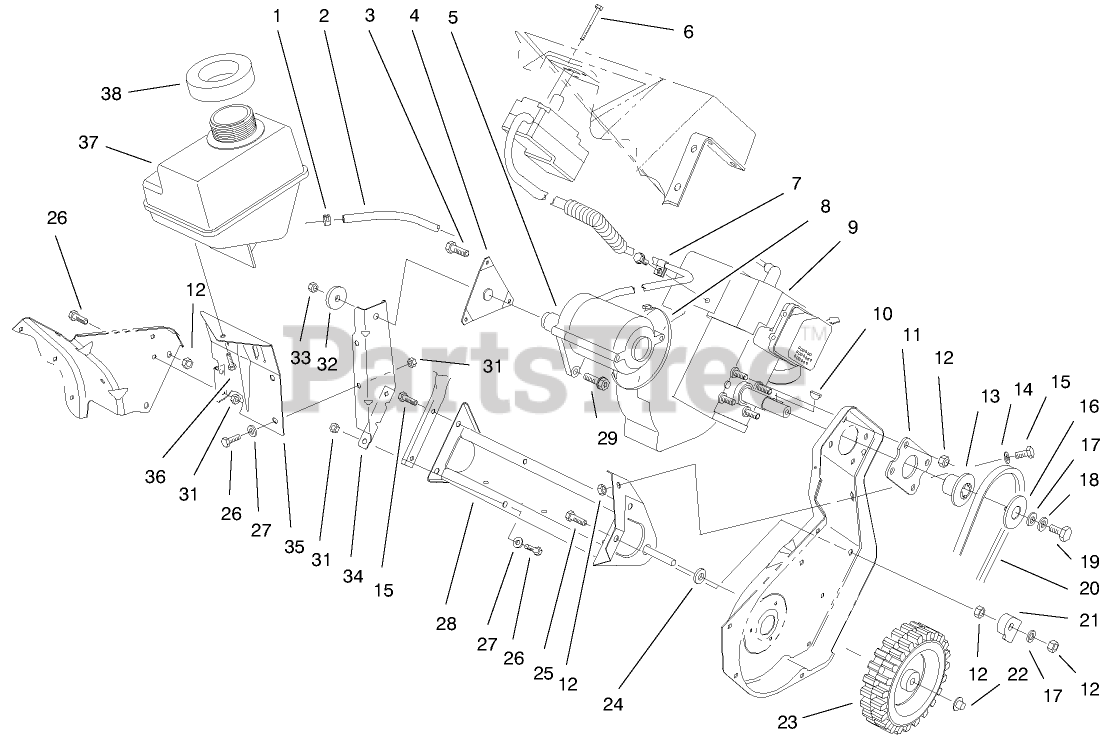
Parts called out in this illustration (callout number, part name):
1	CLAMP-HOSE
2	LINE-FUEL
3	WASHER-LOCK / EXT
3	SCREW
4	BRACKET AND STUD ASM
6	SCREW-PLASTITE
7	CLAMP
8	TIE-CABLE
9	ASM-Engine
10	KEY-WOODRUFF
11	PLATE-ENGINE
12	NUT-LOCK, NI
13	HUB-HALF SHEAVE
14	WASHER-PLAIN
15	SCREW-HH
16	CAP-HALF SHEAVE
17	WASHER-FLAT
18	WASHER-BELLEVILLE
19	SCREW-HH
20	V-BELT
21	GUIDE-CABLE
22	NUT-PUSH
23	WHEEL
24	SPACER-PLASTIC
25	SCREW-HH
26	SCREW-HH
27	WASHER-FLAT
28	FRAME ASM
29	SCREW-HH, TORX
31	NUT-LOCK, NI
32	WASHER-SUPPORT, ENGINE
33	NUT-LOCK, NI
34	SUPPORT-ENGINE
35	BRACKET-TANK
36	SCREW-SHWH, THREAD FORMING
38	SEAL-FOAM
